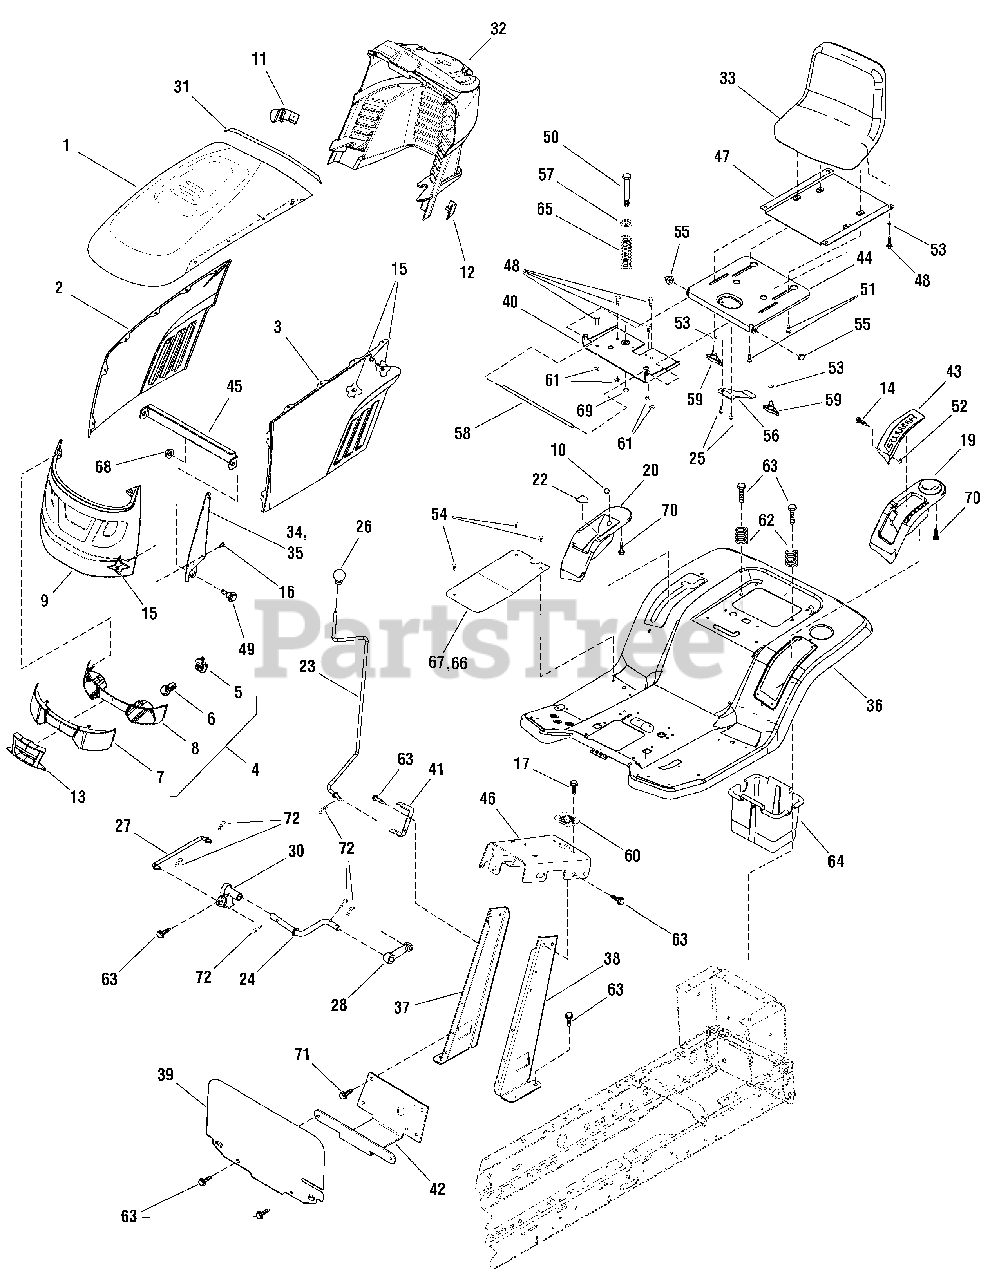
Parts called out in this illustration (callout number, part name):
1	HOOD, 3 Louvers
2	PANEL, Side, Right
3	PANEL, Side, Left
4	HEADLIGHT ASSEMBLY
7	LENS
8	REFLECTOR
11	GUIDE, Hood, Left
12	GUIDE, Hood, Right
13	INSERT, Lightbar
14	SCREW, Hex, Taptit #10C x 1/2
15	NUT-Hex Flange 1/4-20
16	SCREW, Hex Flange Lock 1/4-20 x 5/8
17	SCREW, Self Tap, 1/4-20 x 3/4
19	POD, With Cup Holder
20	POD, With Compartment
22	INDICATOR, Cutting Height
23	ACTUATOR, Cruise
24	ROD, Pivot Cruise
25	SCREW, 1/4-16
26	KNOB, Pull, 1/4-20
27	LINK, Cruise Rod
28	LINK, Cruise
30	LATCH, Cruise
31	STRIP, Trim
33	SEAT, Low Back
34	BRACKET, Pivot Hood, Right
35	BRACKET, Pivot Hood, Left
36	DECK, Seat
37	BRACKET, Dash Support, Right
38	BRACKET, Dash Support, Left
40	BRACKET, Seat Pivot
41	BRACKET, Support, Cruise
42	STIFFENER, Steering
44	SUPPORT, Seat
45	BRACKET, Hood Stiffener
46	CLUTCH ROD SUPPORT
47	ADAPTOR PLATE, Seat
48	BOLT, HEX, 5/16-18 x 5/8
49	BOLT, Shoulder, 3/8-16
50	BOLT, Shoulder, 1/4-20 x 5/16
51	BOLT, Shoulder, 5/16-18
52	NUT, Mclean #10-24
53	WASHER, Flat, 5/8
54	FASTENER, Panel
55	CAP, Push-on
56	SPRING, Leaf
57	WASHER, Cup
60	BEARING, Steering
61	NUT, Nylock, 5/16-18
62	SPRING, Compression
63	CAPSCREW, 5/16-18 x 3/4
64	CONTAINER, Battery
65	SPRING, Compression
66	MAT, Molded, Left
67	MAT, Molded, Right
68	NUT, Hex Flange, 3/8-16
69	NUT, Hex Flange, 1/4-20
70	SCREW, 1/4-20 x 1/2
71	SCREW, 1/4-20 x 3/8
72	HAIRPIN
